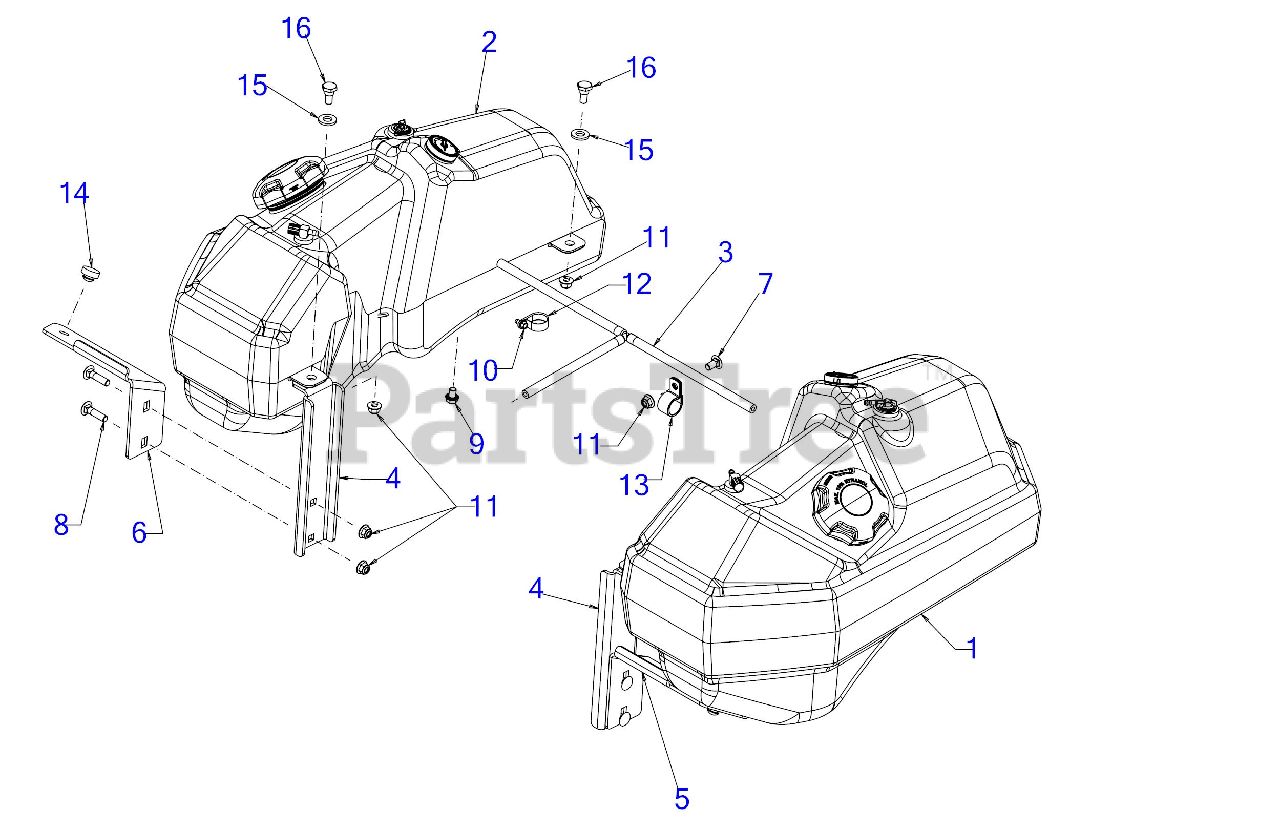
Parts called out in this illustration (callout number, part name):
1	FUEL TANK ASSEMBLY (RH) (7.25 GAL)
2	FUEL TANK ASSEMBLY (LH) (7.25 GAL)
3	FUEL LINE ASSEMBLY
7	CARRIAGE BOLT 3/8-16 x .750 GR5
8	CARRIAGE BOLT 3/8-16 x 1.50
9	SCREW 3/8-16 x .500 GR5
10	SCREW 1/4-20 X.500
12	DRAIN HOSE CLAMP
13	HOSE CLAMP 1.0"
14	RUBBER BUMPER 1.000 x .313
15	FLAT WASHER
16	SHOULDER SCREW .498 DIA x .340
